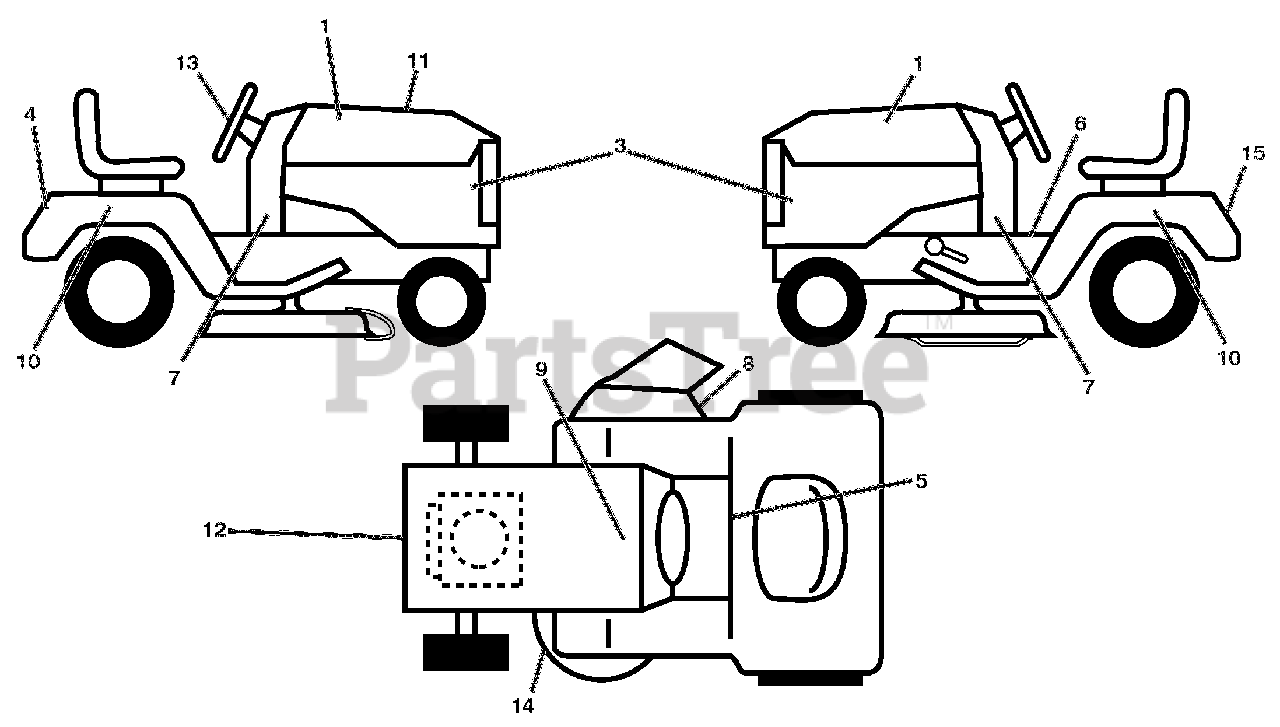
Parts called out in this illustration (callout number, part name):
1	DECAL.HOOD.RH.PRECISION.ARIENS
3	DECAL.SDPNL.PWRDBY KOHL.ARIENS
4	Decal, Fender
5	DECAL.FENDER
6	DECAL, WARNING START INST.
7	DECAL DASH LOWER
8	DECAL.MOWER.WARN.KEEP HAND AWY
9	DECAL.BAT.DAN/POI P/L SYM.WPN
10	DECAL FENDER SIDE HYDRO ARIENS
11	DECAL REPLACEMENT
12	DECAL ENGINE
13	DECAL.WHEEL.STEER.ARIENS
14	DECAL.V-BELT.SCH.42/46"MEC/ELE
15	Decal Fender Service
